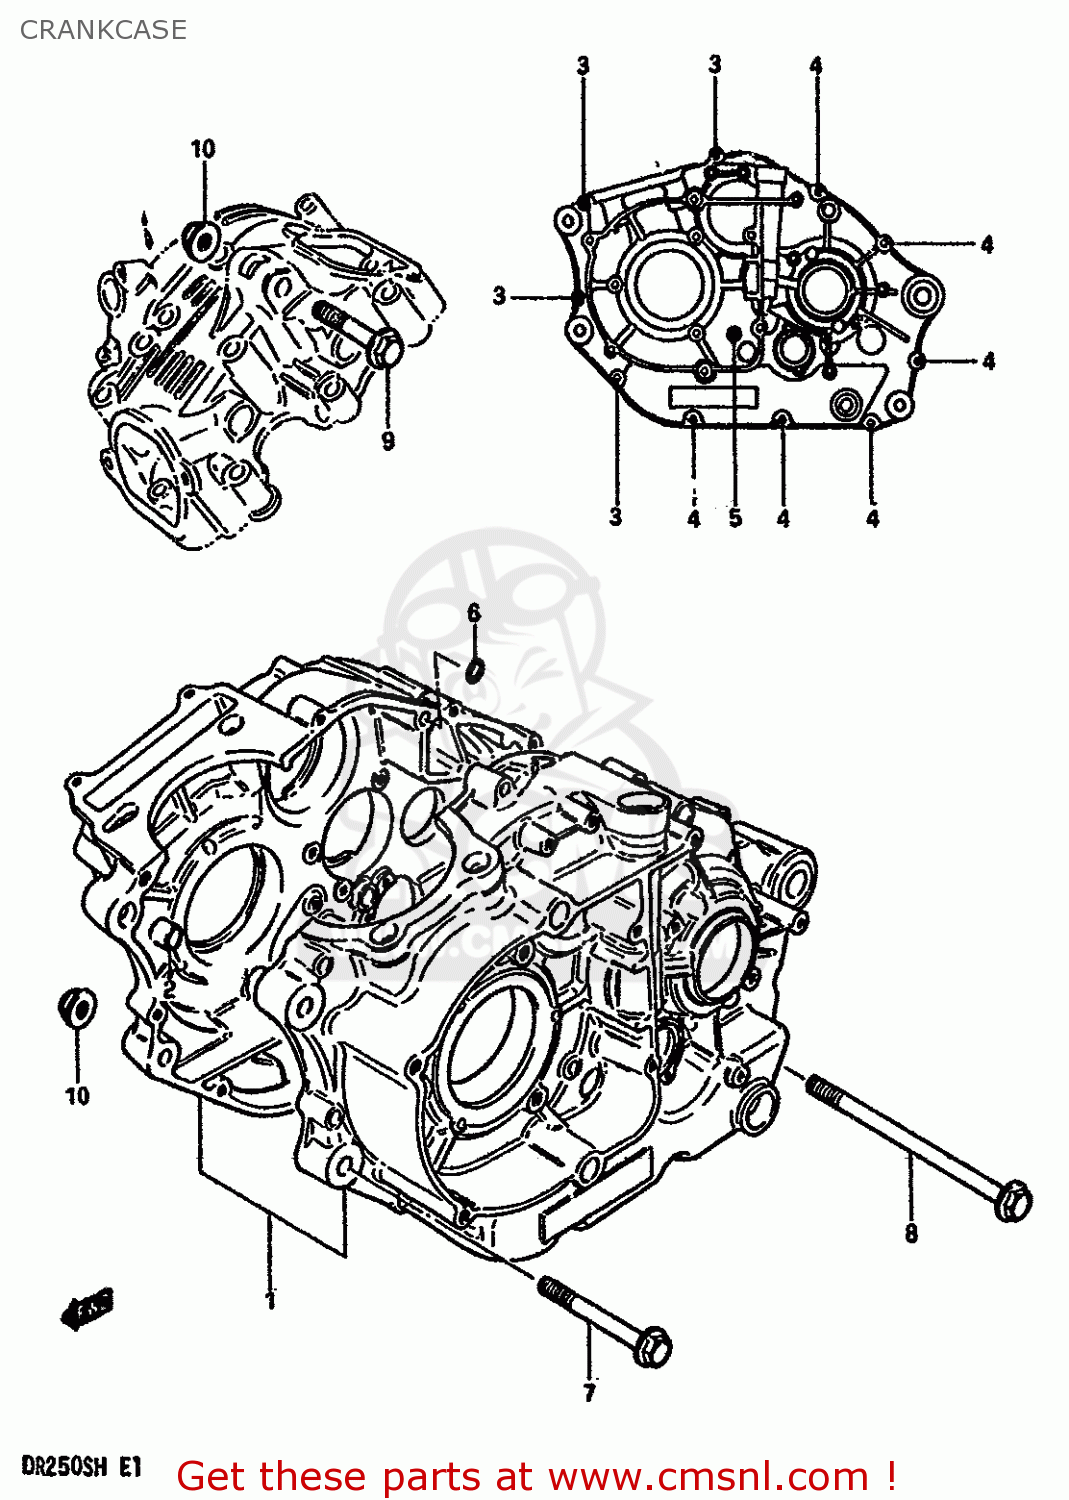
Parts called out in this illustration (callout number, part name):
1	CRANKCASE ASSEMBLY
2	PIN
3	BOLT 6X35
4	BOLT
5	BOLT (6X55)
6	O-RING
7	BOLT 8X67
8	BOLT
9	BOLT 8X50
10	NUT
